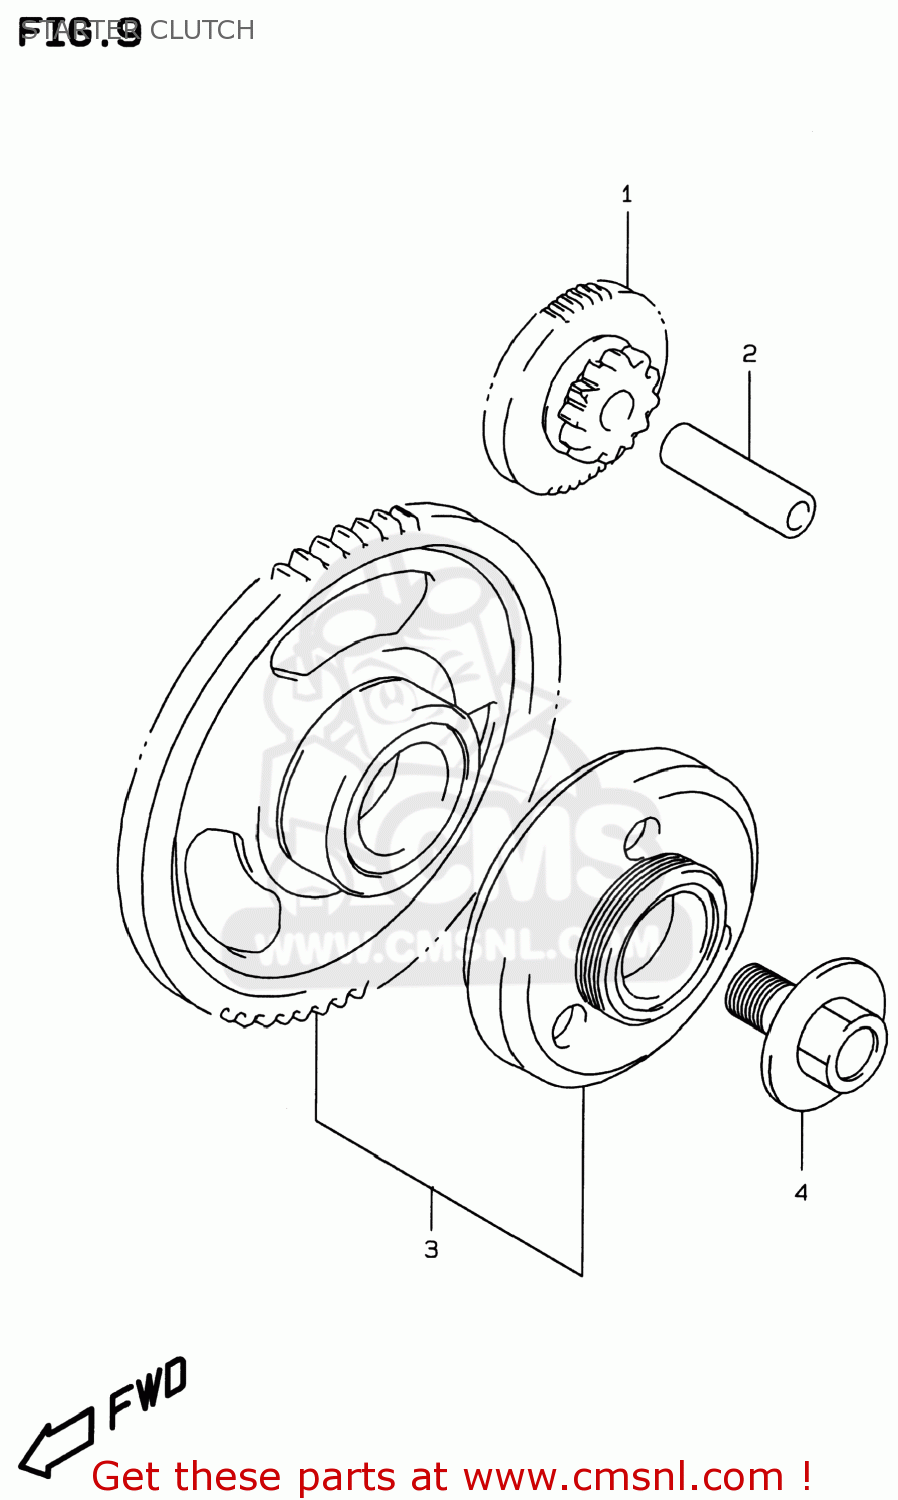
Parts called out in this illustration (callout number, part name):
1	GEAR,STARTER IDLE(NT:12,53)
2	PIN(7X11X42)
3	CLUTCH SET,STARTER
4	BOLT(14X21)
